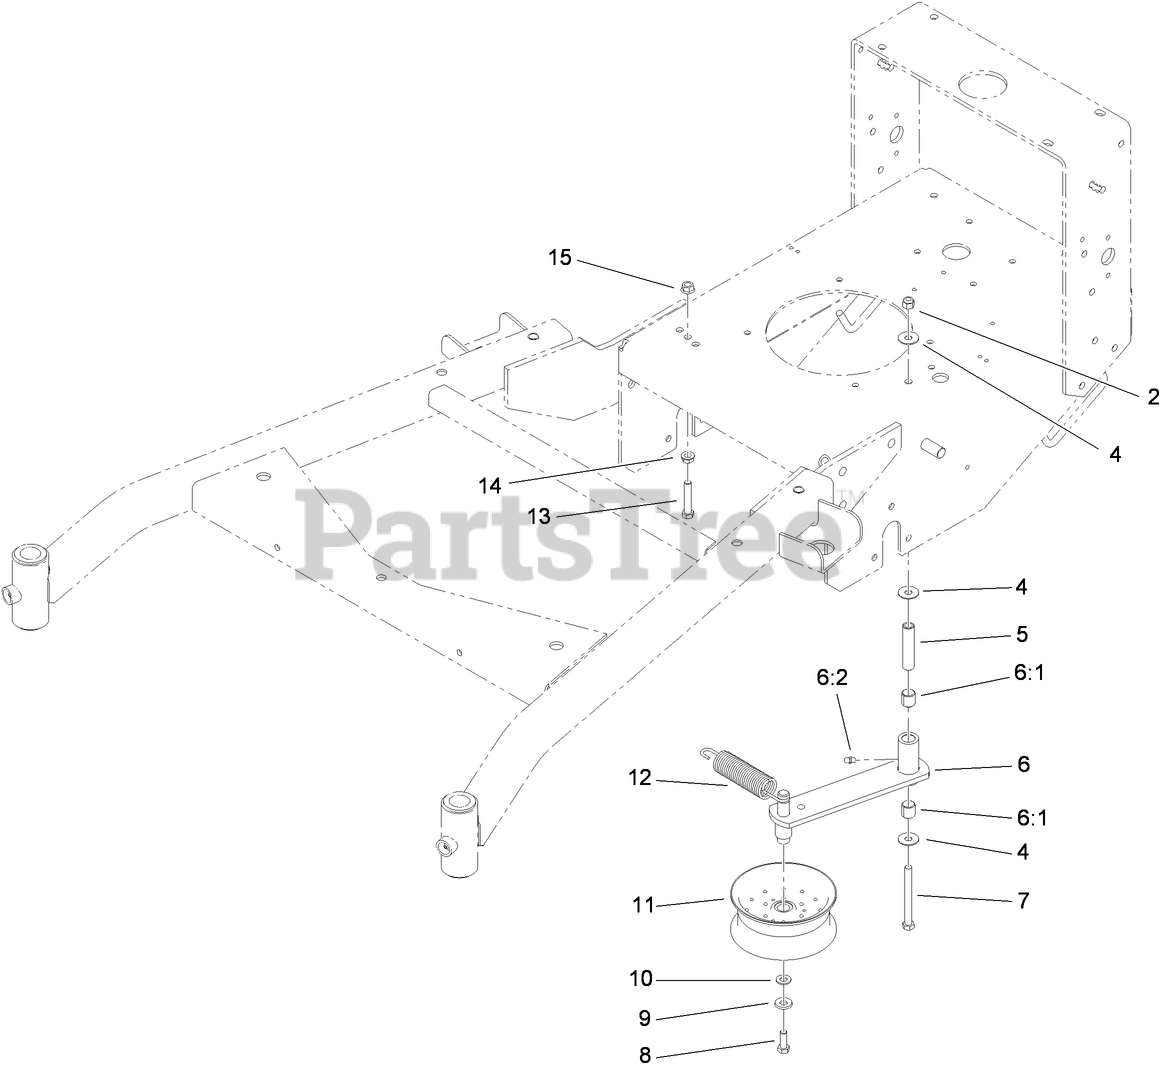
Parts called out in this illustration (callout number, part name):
2	NUT-LOCK, NI
4	WASHER
5	TUBE-IDLER
6	IDLER ARM ASM
6:1	SLEEVE-BEARING
6:2	FITTING-GREASE
7	SCREW-HH
8	SCREW-HH
9	WASHER-BELLEVILLE
10	WASHER-FLAT
11	PULLEY-IDLER
12	SPRING-EXTENSION
13	SCREW-HH
14	NUT-HHF, WHIZ
15	NUT-HF
